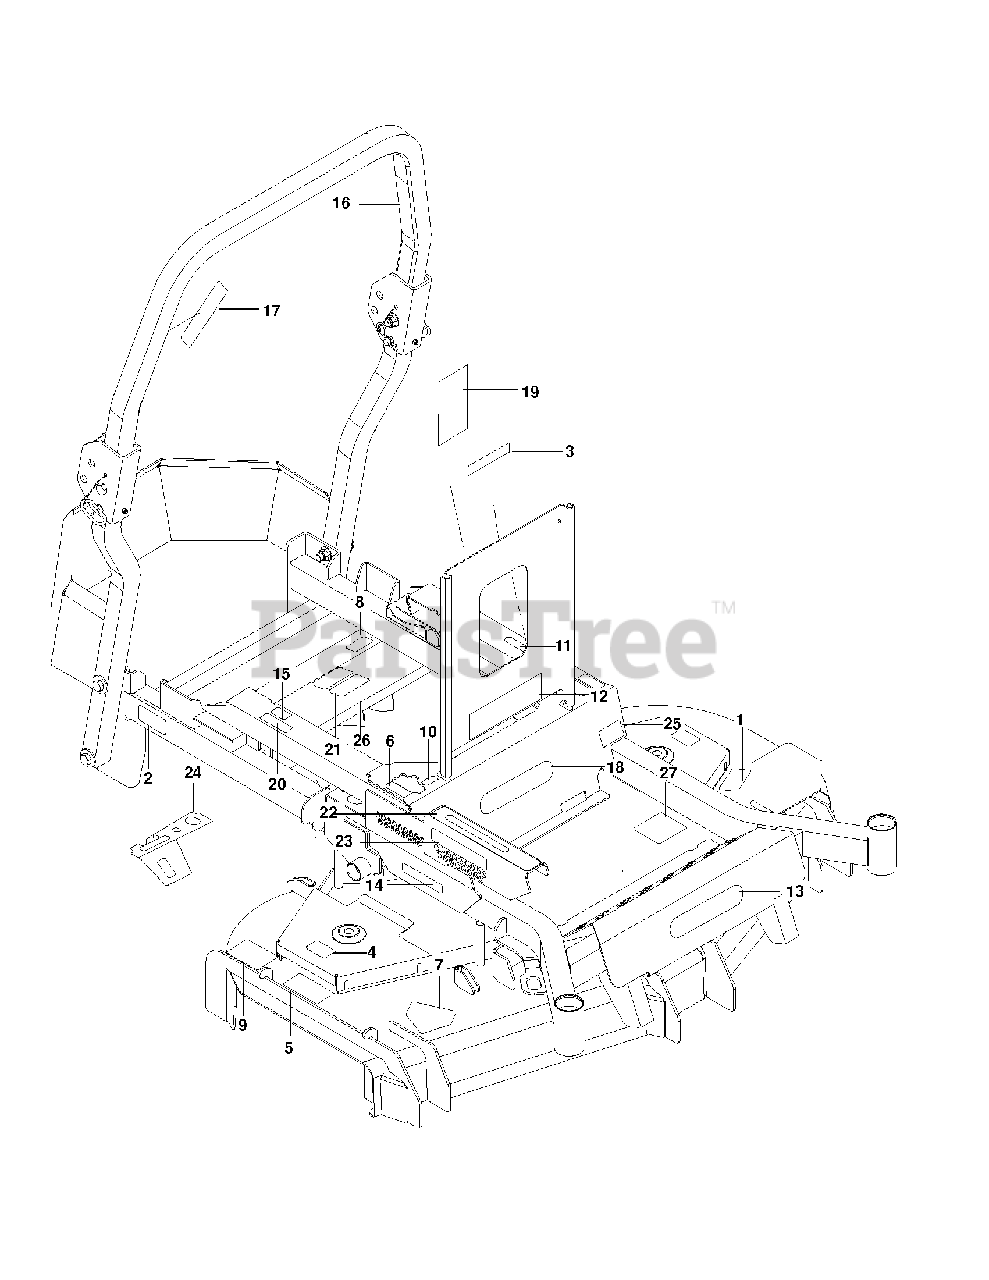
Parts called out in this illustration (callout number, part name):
2	DECAL, BELT DRIVE
4	DECAL, NO STEP
5	DECAL, EURO SEVERING
7	DECAL, CPSC
8	DECAL, FUEL
9	DECAL, CAUTION
10	DECAL, TRACKING
11	DECAL, PARK BRAKE
12	DECAL, WARNING
14	DECAL, COMMERCIAL
16	DECAL, ROPS
17	DECAL, ROPS, WARNING
19	DECAL, SERVICE
20	DECAL, WARNING SPARK ARRESTOR
22	DECAL, HEIGHT
23	DECAL, HEIGHT
25	DECAL, FLAG
26	DECAL, OIL TANK
27	DECAL, BELT ROUTING
